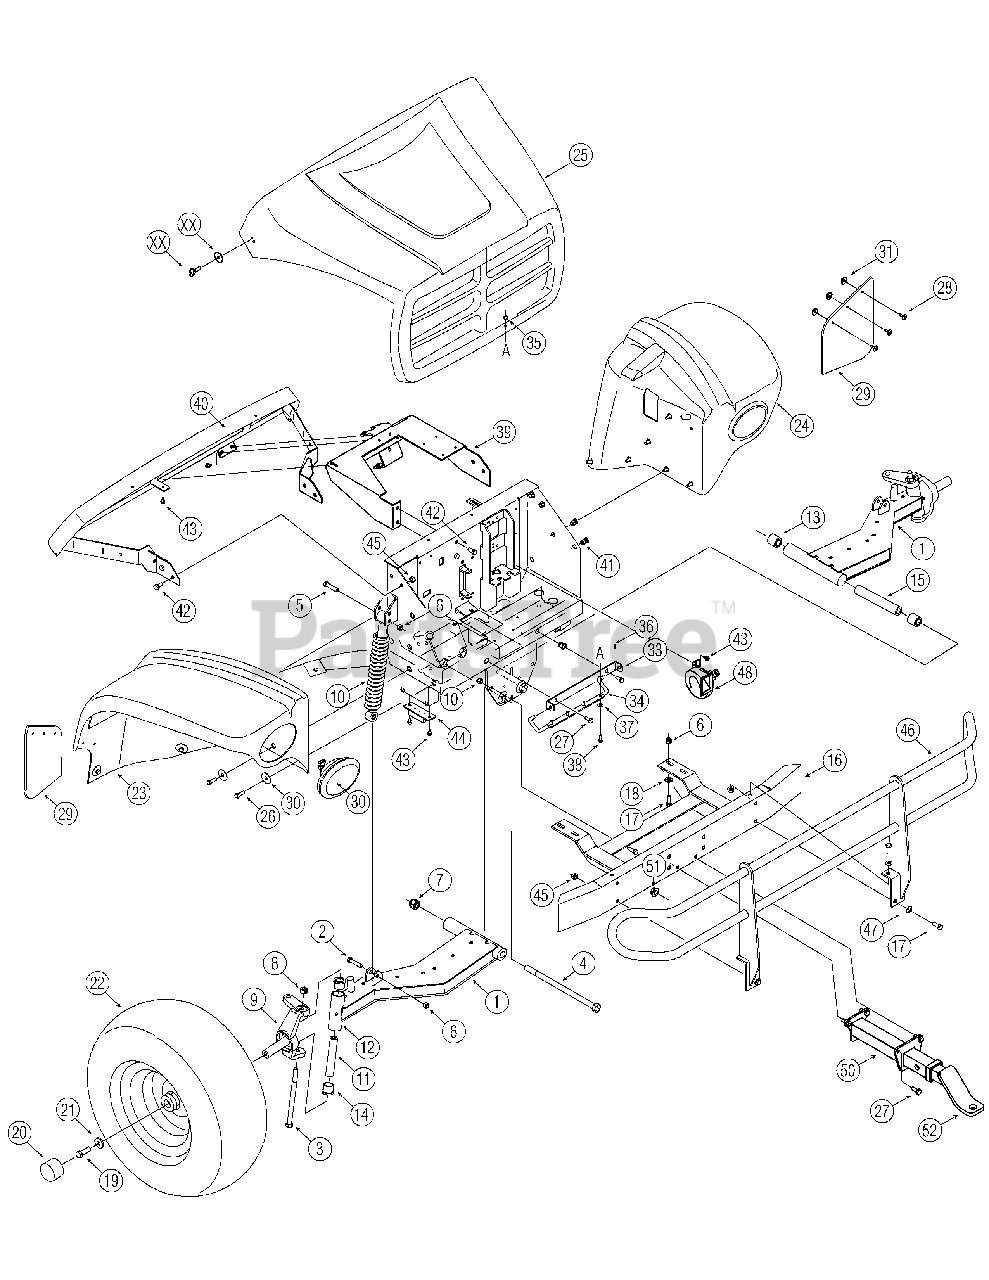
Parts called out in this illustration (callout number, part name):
1	Axle Assembly, Right-front (Incl. Ref 12 - 15)
1	Axle Assembly, Left-front (Incl. Ref 12 - 15)
2	Hex Screw, 3/8-16 x 1.75
3	Hex Screw, 1/2-13 x 7.0, Gr5
4	Hex Screw, 5/8-11 x 11.13, Gr5
5	Hex Screw, 3/8-16 x 2.25
6	Nut, Hex Lock, Nylon, 3/8-16, Gr5
7	Nut, Hex Lock, Nylon, 5/8-11, Gr5
8	Nut, Hex Lock, 1/2-13
9	Steering Control Knuckle, LH
10	Shock Absorber, 2.9 Stroke
11	Tube, .875 x .50 x 4.75
12	Grease Fitting
13	Bearing, .63 ID x 1.19 OD
14	Bushing, Steering
15	Spacer, .645 ID x 1.063 OD
18	Flat Washer,.406 x.875 x.059
19	Hex Screw, 1/2-13 x 1.25, Gr5
21	Flat Washer,.531 x 1.25 x.181
22	Wheel Ass’y, 22 x 11 x 10, RH, All Terr.
22	Wheel Ass’y, 22 x 11 x 10, LH, All Terr.
23	Panel, Right Fender, Red
24	Panel, Left Fender, Red
25	Panel, Hood, Red
26	Hex Screw 5/16-18 x 1.00 Gr 5
27	Hex Screw, 5/16-18 x.75
28	Pop Rivet
30	Washer, Bell,.39 x 1.38 x.062
31	Flat Washer, .194 x .62 x .063
32	Head lamp Assembly
35	Nut, Hex Lock, 1/4-20
36	Cotter Pin, Internal, 1.42
37	Washer, Flat,.271 x.63 x.065
38	Hex Screw, 1/4-20 x.75
41	Insert Nut, 5/16-18
42	Hex Screw, 3/8-16 x.75
43	Screw, Self-tapping, 1/4-20 x.5
44	Suspension Bumper
45	Flange Lock Nut, 3/8-16
46	Brush Guard
47	Washer, Flat, 406 x .810 x .051
48	Horn
49	Flat Washer .030 .625 x .090
50	Front Hitch Assembly
51	Flange Lock Nut
52	Hitch Accessory
